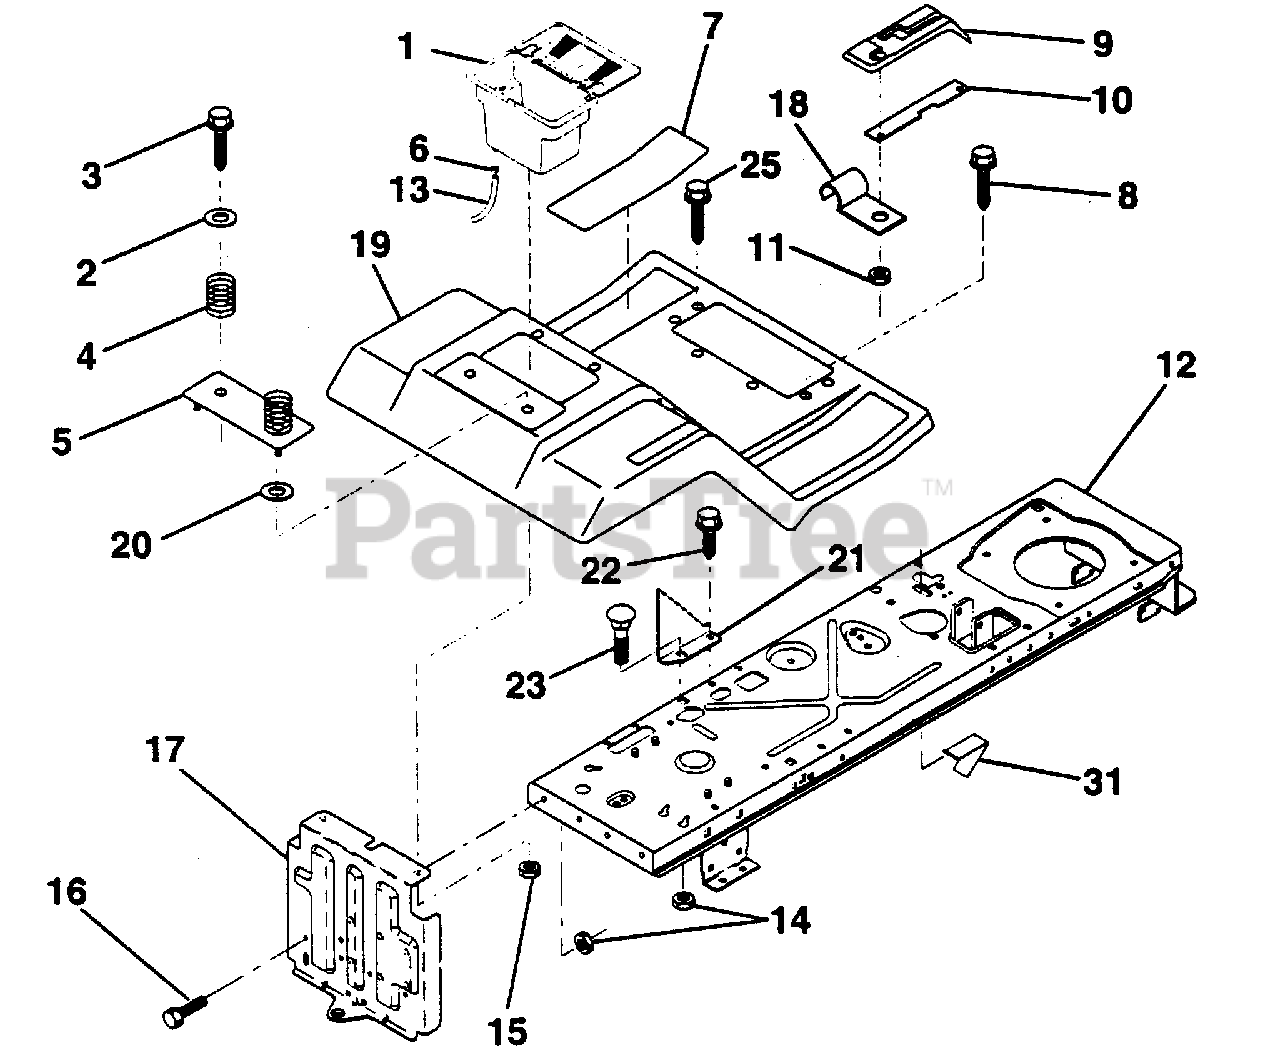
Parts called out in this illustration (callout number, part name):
1	Case Asm. Battery (AYP part number)
2	Washer 13/32 x 1-1/4 x 12 Ga. (AYP part number)
3	Screw Thdrol. 3/8-16 x 3/4 (AYP part number)
4	Spring seat (AYP part number)
5	Plate Asm. Pnt Battery Fender (AYP part number)
6	Clamp Hose Olive (AYP part number)
7	Pad Footrest (AYP part number)
8	Screw Thdrol. 5/16-18 x 3/4
9	Console Shf. 6sp W/Ign. (AYP part number)
10	Plate Lock Shift (AYP part number)
11	Nut Self Thd. Wsh-Hd 1/4 (AYP part number)
12	Chassis Asm. Weldment (AYP part number)
13	Tube Plastic (AYP part number)
14	Nut Lock Hex W/Ins 5/16-18 (AYP part number)
15	Nut Keps Hex 1/4-20 (AYP part number)
16	Bolt Hex Hd. 5/16-18 x 3/4 (AYP part number)
17	Drawbar Asm. (AYP part number)
18	Clip Insulated (AYP part number)
19	Fend/Foot Asm. Pnt Shf. Fnd. (AYP part number)
20	Washer 9/32 x 7/8 x 13 Ga. (AYP part number)
21	Bracket Stop Depth (AYP part number)
22	Screw Thdrol 5/16-18 x 1/2 (AYP part number)
23	Bolt Rdhdsqnk. 5/16-18 x 3/4 (AYP part number)
25	Scr-Hex Wsh Rol 5/16-18 x 1 (AYP part number)
31	Switch Activator (AYP part number)
